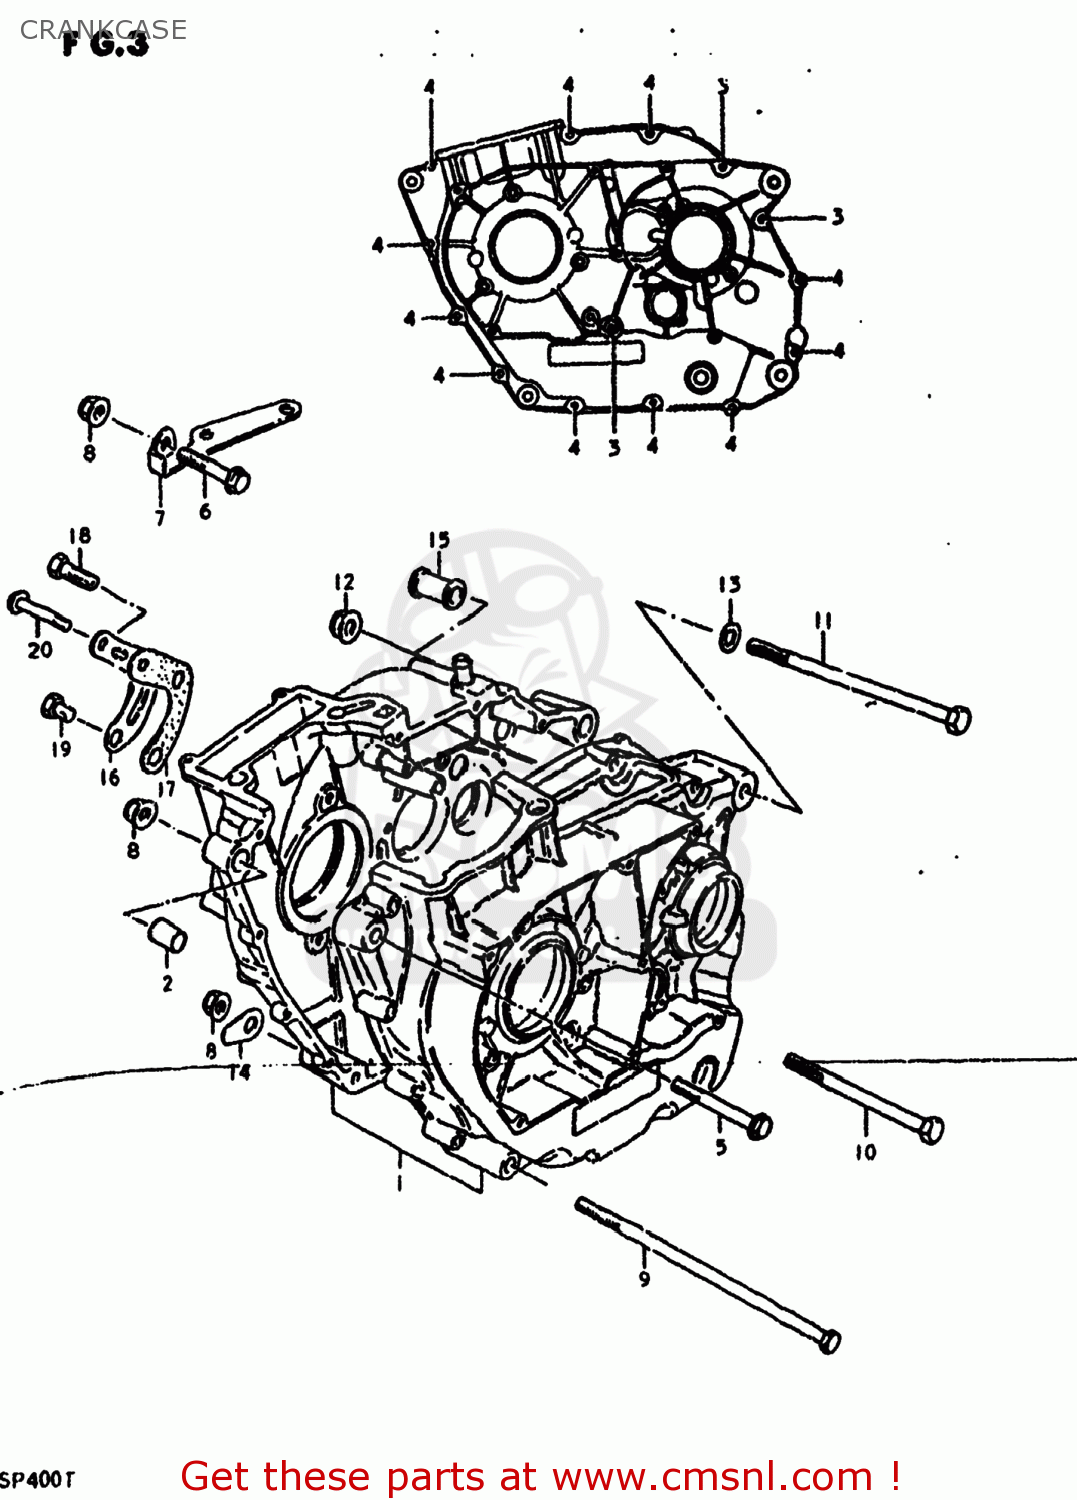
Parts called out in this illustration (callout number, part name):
1	CRANKCASE SET
2	PIN
3	SCREW
4	SCREW (6X35)
5	BOLT (8X70)
6	BOLT
7	PIPE,CYLINDER HEAD OIL
8	NUT
9	BOLT(10X190)
10	BOLT 10X115
11	BOLT 10X155
12	NUT
13	WASHER
14	WASHER
15	SPACER
16	CAP,OIL GALLERY
17	GASKET,OIL GALLERY (MCA)
18	BOLT,UNION
19	PLUG
20	BOLT
